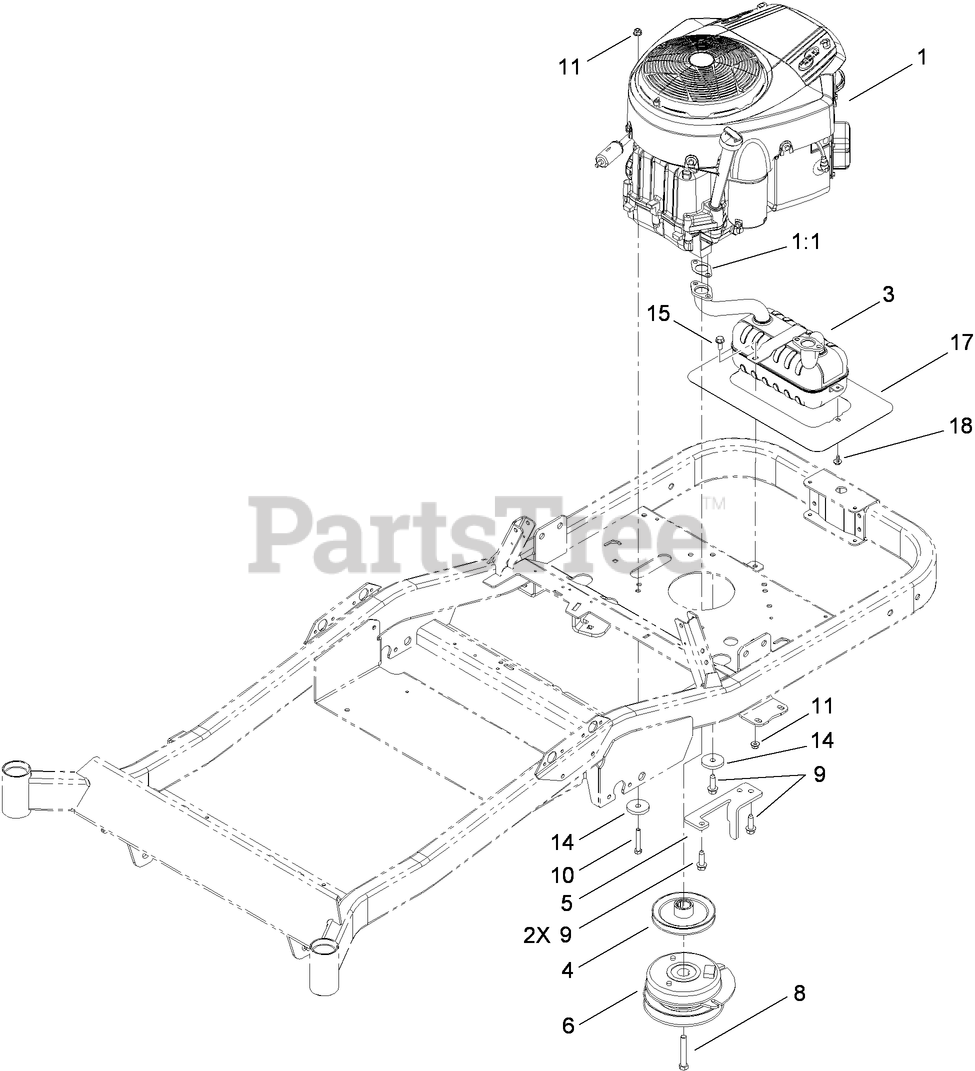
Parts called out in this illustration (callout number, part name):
1	ENGINE-BRIGGS, 22HP PROFESSIONAL
1:1	GASKET-EXHAUST
3	MUFFLER-BRIGGS TWIN
4	PULLEY-ENGINE
5	BRACKET-STOP, PTO
6	CLUTCH-ELECTRIC, PTO
8	SCREW-HH
9	SCREW-TAPTITE
10	SCREW-HH
11	NUT-HF, NI
14	WASHER-PLAIN
15	SCREW-HHF
17	SHIELD-HEAT
18	SCREW-HHFTF
